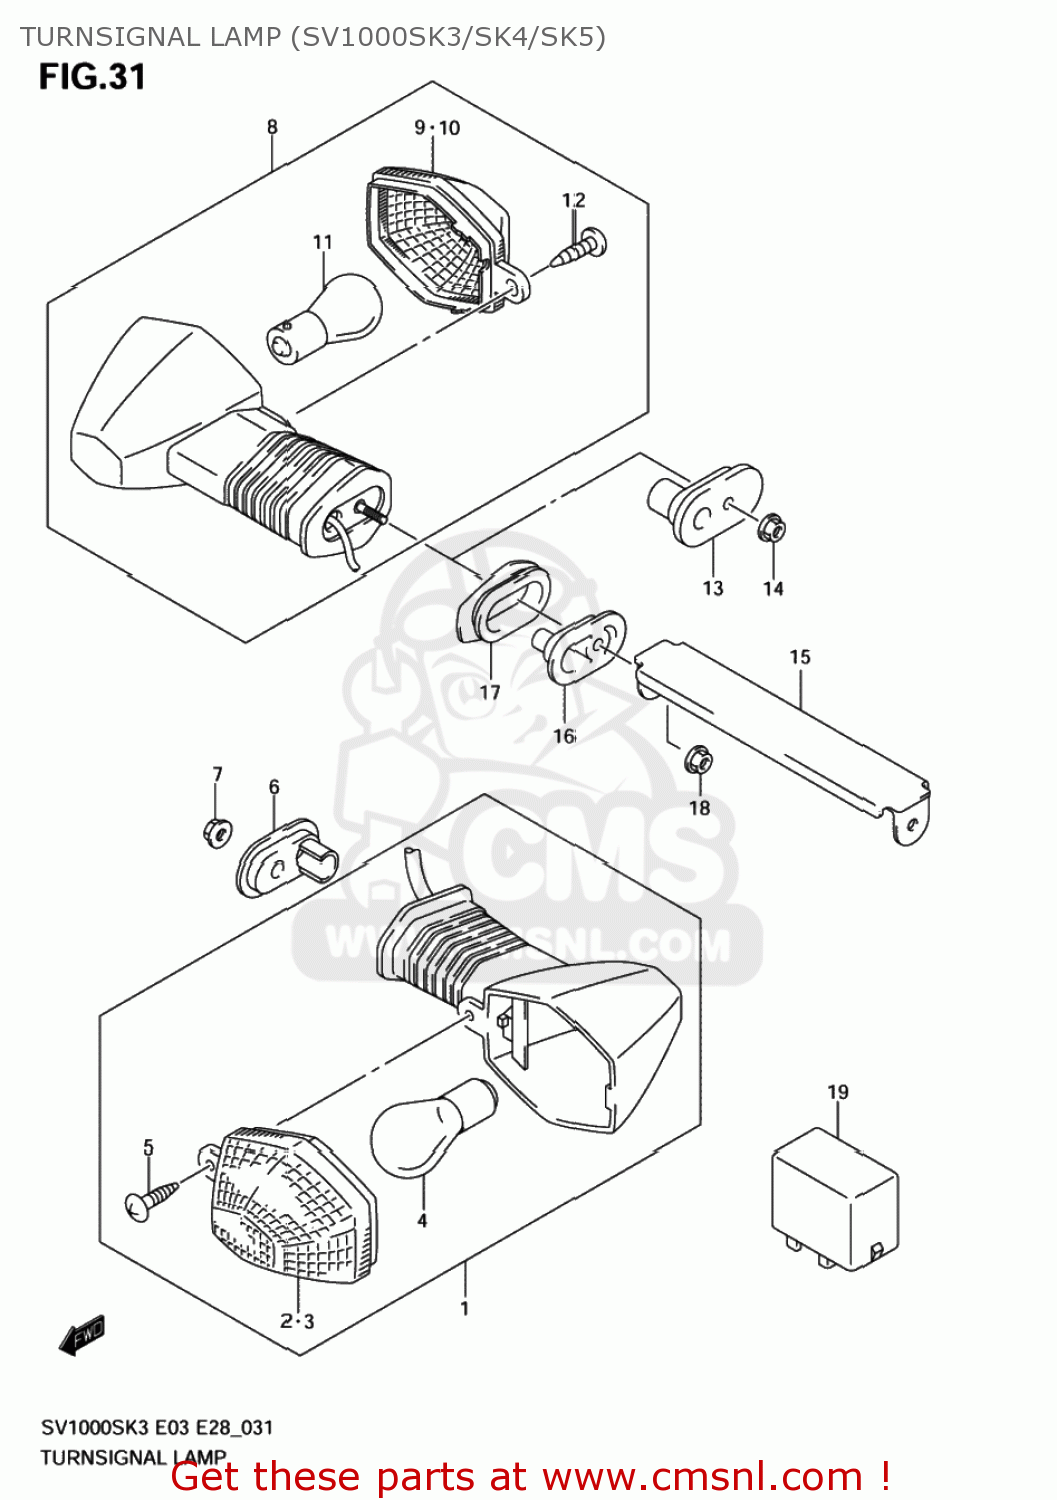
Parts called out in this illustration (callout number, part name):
1	LAMP ASSY,FR TURN,R
2	LENS
3	LENS
4	BULB(12V21W)
5	SCREW
6	PLATE,TURNSIGNAL LAMP
7	NUT
8	LAMP ASSY,RR TURNSIGNAL,R
9	LENS
10	LENS
11	BULB(12V21W)
12	SCREW
13	PLATE,TURNSIGNAL LAMP
14	NUT
15	BRACKET,RR TURNSIGNAL
16	PLATE,RR TURN SIGNAL
17	CUSHION,RR
18	NUT
19	RELAY ASSY,TURNSIGNAL LAMP
